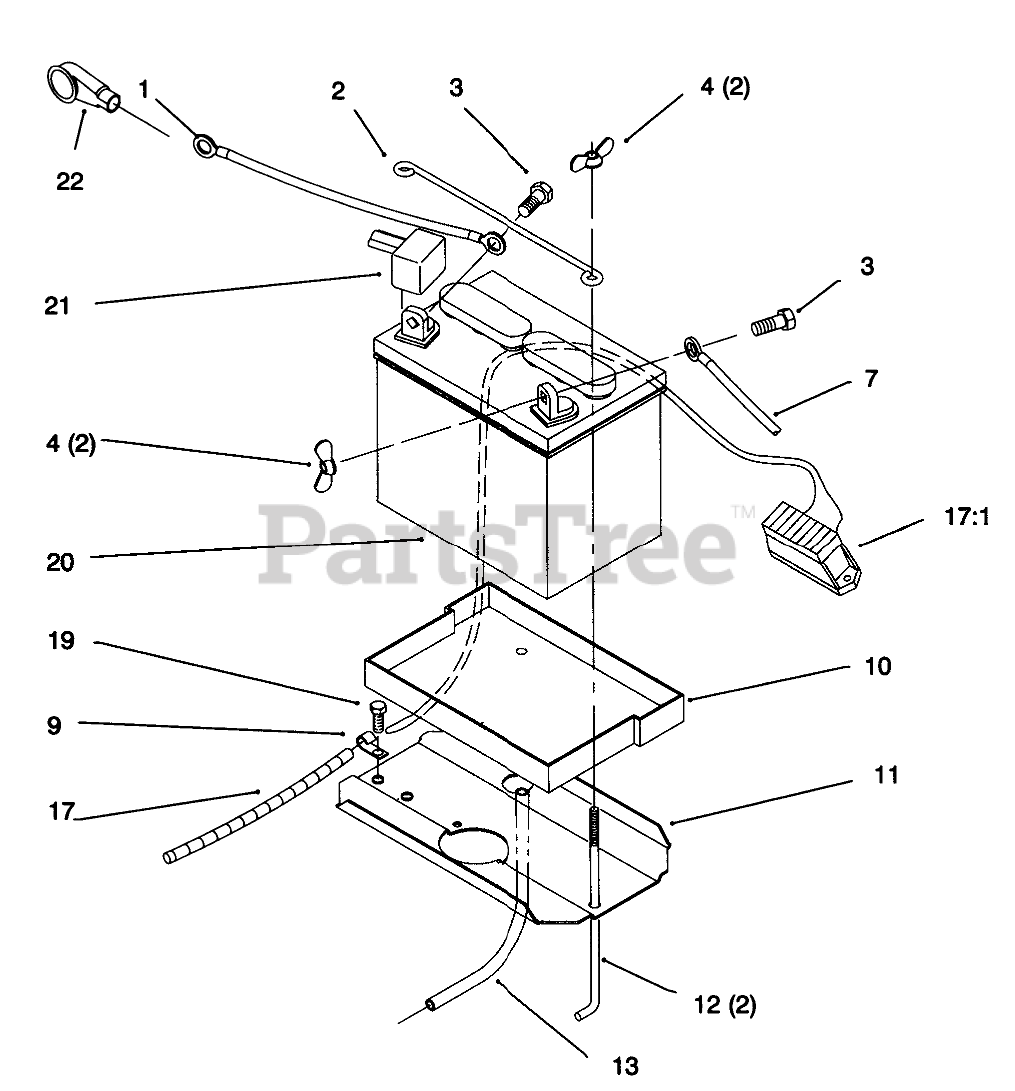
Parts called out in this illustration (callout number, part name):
1	Cable-Battery Red (Only On: 72103)
1	Cable-Battery Red (Only On: 72042, 72043, 72062, 72063)
2	ROD-BATTERY HOLD DWN
3	SCREW-HH
4	NUT-WING
7	Cable-Battery Black (Only On: 72042, 72043, 72062, 72063)
7	Cable-Battery Black (Only On: 72103)
9	CLIP
10	TRAY-BATTERY
11	PLATE-BATTERY
13	TUBE-21" BATTERY DRAIN
17	Harness-Wire (Only On: 72103)
17	Harness-Wire (Only On: 72043, 72063)
17	Harness-Wire (Only On: 72042, 72062)
17:1	FUSE-HOLDER 4 WAY
19	SCREW-HWHTF
20	Battery (Only On: 72042, 72043, 72062, 72063)
20	Battery (Only On: 72103)
20	Battery (Only On: 72042, 72062)
21	Boot
22	Boot-Terminal Insulator (Only On: 72103)
